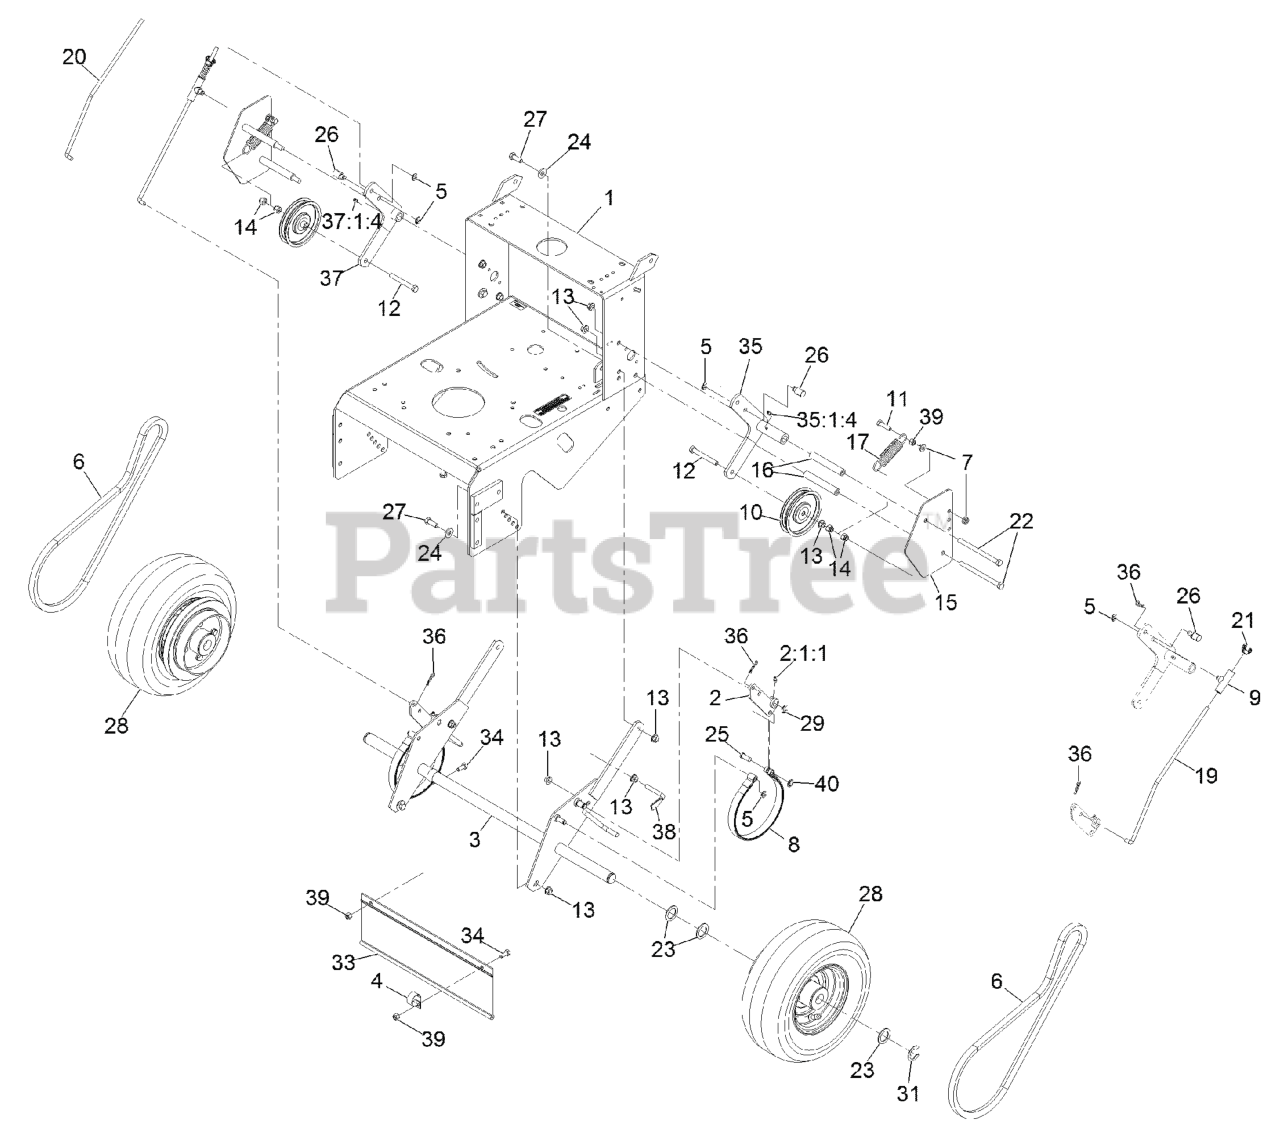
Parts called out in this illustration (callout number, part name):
1	ASM, METRO ENGINE DECK W/
2	ARM-BRAKE
2:1:1	ASM,BUSHING/ZERK
4	CLAMP-R
5	RING-RETAINING
6	BELT,WHEEL DRIVE
8	BAND-BRAKE
9	SWIVEL-BRAKE
10	IDLER-WHEEL, DRIVE
11	SCREW-HH, SPECIAL
12	SCREW-HH
13	NUT-HHF, WHIZ
14	NUT-LOCK, NI
15	SHIELD-WHEEL, DRIVE
16	SPACER-SHIELD
17	SPRING-EXTENSION
19	LINKAGE-BRAKE, LH
20	LINKAGE-BRAKE, RH
21	WINGNUT-NYLOCK
22	SCREW-HH
23	WASHER-SPACER
24	WASHER-BELLEVILLE
25	PIN-CLEVIS
26	SWIVEL-DRIVE LEVER, 3/8 L
27	SCREW-HH
28	DRIVE WHEEL ASM
29	RING-RETAINING, EXTERNAL
31	RING-SNAP
33	SHIELD-TRAILING
34	SCREW-HH
35	ARM-IDLER, LH
35:1:4	FITTING-GREASE
36	PIN-COTTER
37	ARM-IDLER, RH
37:1:4	FITTING-GREASE
38	SCRAPER
39	NUT-LOCK, NI
40	RING-RETAIN,PUSH,EXT,FLAT
